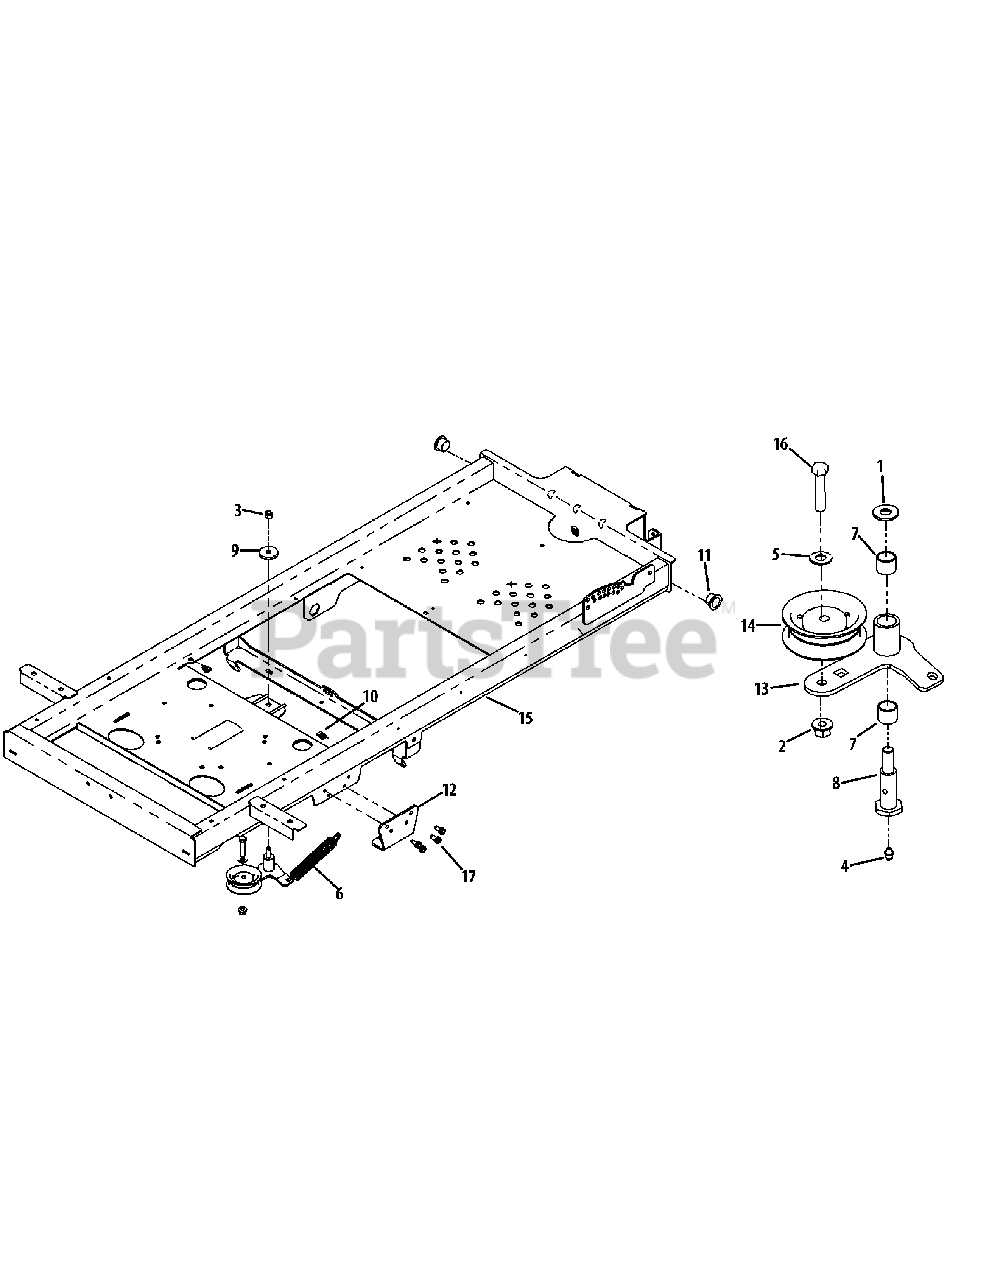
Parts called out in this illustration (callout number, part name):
1	Flat Washer, 3/8
2	Flange Lock Nut, 3/8-16
3	Nylock Nut, 7/16-14
4	Grease Fitting, 1/4-28 x 3/16
5	Washer, 3/8
6	Extension Spring, 1.00 x 5.00
7	Bearing Sleeve
8	Shoulder Bolt
9	Flat Washer, 7/16 x 1.75
10	U-Nut, 1/4-20
11	Bronze Bushing, 1.00 ID x 1.50 OD
12	Transmission Mounting Bracket
13	Idler Arm
14	Flat Idler Pully
15	Frame Assembly
16	Hex Cap Screw, 3/8-16 x 1-3/4
17	Self Tapping Screw, 5/16-18 x .750
